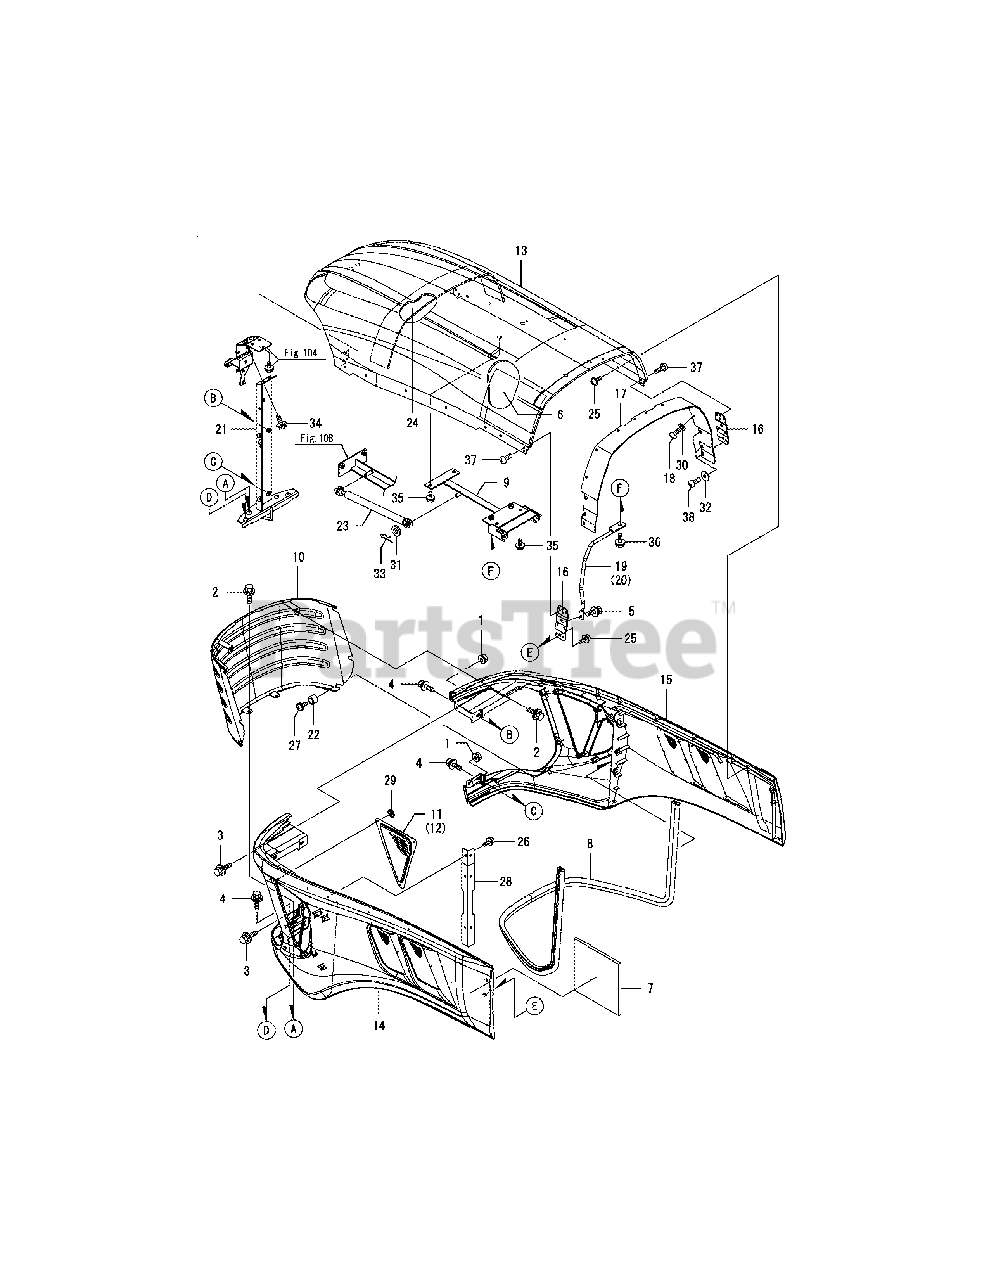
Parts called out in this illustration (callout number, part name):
1	NUT W/WASHER 6
6	INSULATOR, HOOD
7	INSULATOR, HOOD LOWER
9	HINGE ASSY, HOOD
10	NET ASSY, HOOD
13	HOOD ASSY, TOP
14	HOOD ASSY, LOWER L
15	HOOD ASSY, LOWER R
16	BRACKET, HOOD LOWER
18	SCREW, #10-32X3/8
19	ROD CMP, HOOD LH
20	ROD CMP, HOOD RH
21	STAY ASSY, LOCK
22	COLLAR, 10X15X10
23	SPRING, GAS 700
24	URETHANE, HOOD UPPER
28	STAY, HOOD SIDE
30	WASHER 5, POLISHED
31	WASHER 10,POLISHED
34	BOLT M 8X 12 PLATED
35	BOLT M 8X 12 PLATED
36	BOLT M 8X 16 PLATED
